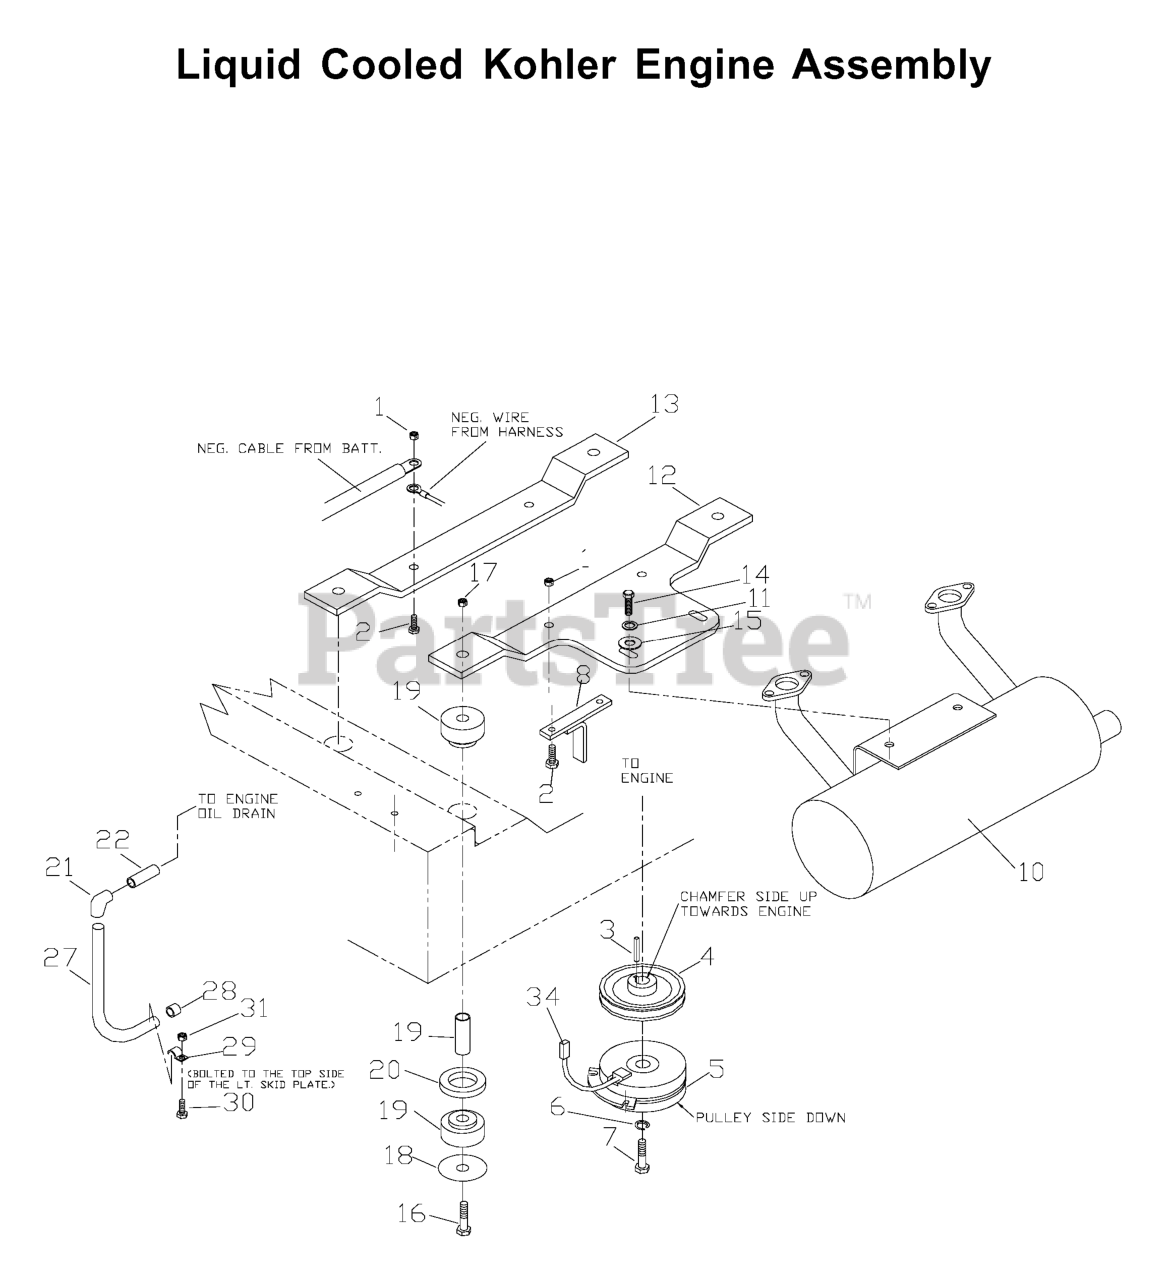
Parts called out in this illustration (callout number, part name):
1	NUT 5/16C CENTERLOCK
2	HCS 5/16C X 1 3/4
3	KEY 1/4" SQ X 1 7/8"
5	ELECTRIC CLUTCH W/CABLE
6	WASHER 7/16 LOCK
7	BOLT 7/16F X 2 1/2
8	CLUTCH TIE DOWN
9	KOHLER PIGTAIL L/C
10	MUFFLER KOHLER GEN II
11	WASHER.LOCK.HVY.HLCL.SPR.5/16
12	REAR ENGINE MOUNT
13	ENGINE MOUNT
14	HCS 5/16C X 3/4
15	WASHER 5/16 FLAT
16	HCS 1/2C X 3 1/4
17	NUT 1/2-13 HEX NYLOC ZD
18	ISOLATOR WASHER
20	ISOLATOR SPACER
21	90 DEG.ELBOW 3/8NPT
22	PIPE 3/8 NPT 1-1/2
23	TEMP GAUGE DATCON #100182
24	BRACKET-TEMP GAUGE
25	HARNESS-TEMP GAUGE
26	HCS 5/16-18X2
27	OIL DRAIN HOSE
30	HCS 1/4C X 3/4 HCS
31	NUT 1/4C CENTER LOCK
32	CHOKE CONTROL, COMPLETE
34	CLUTCH HARNESS
